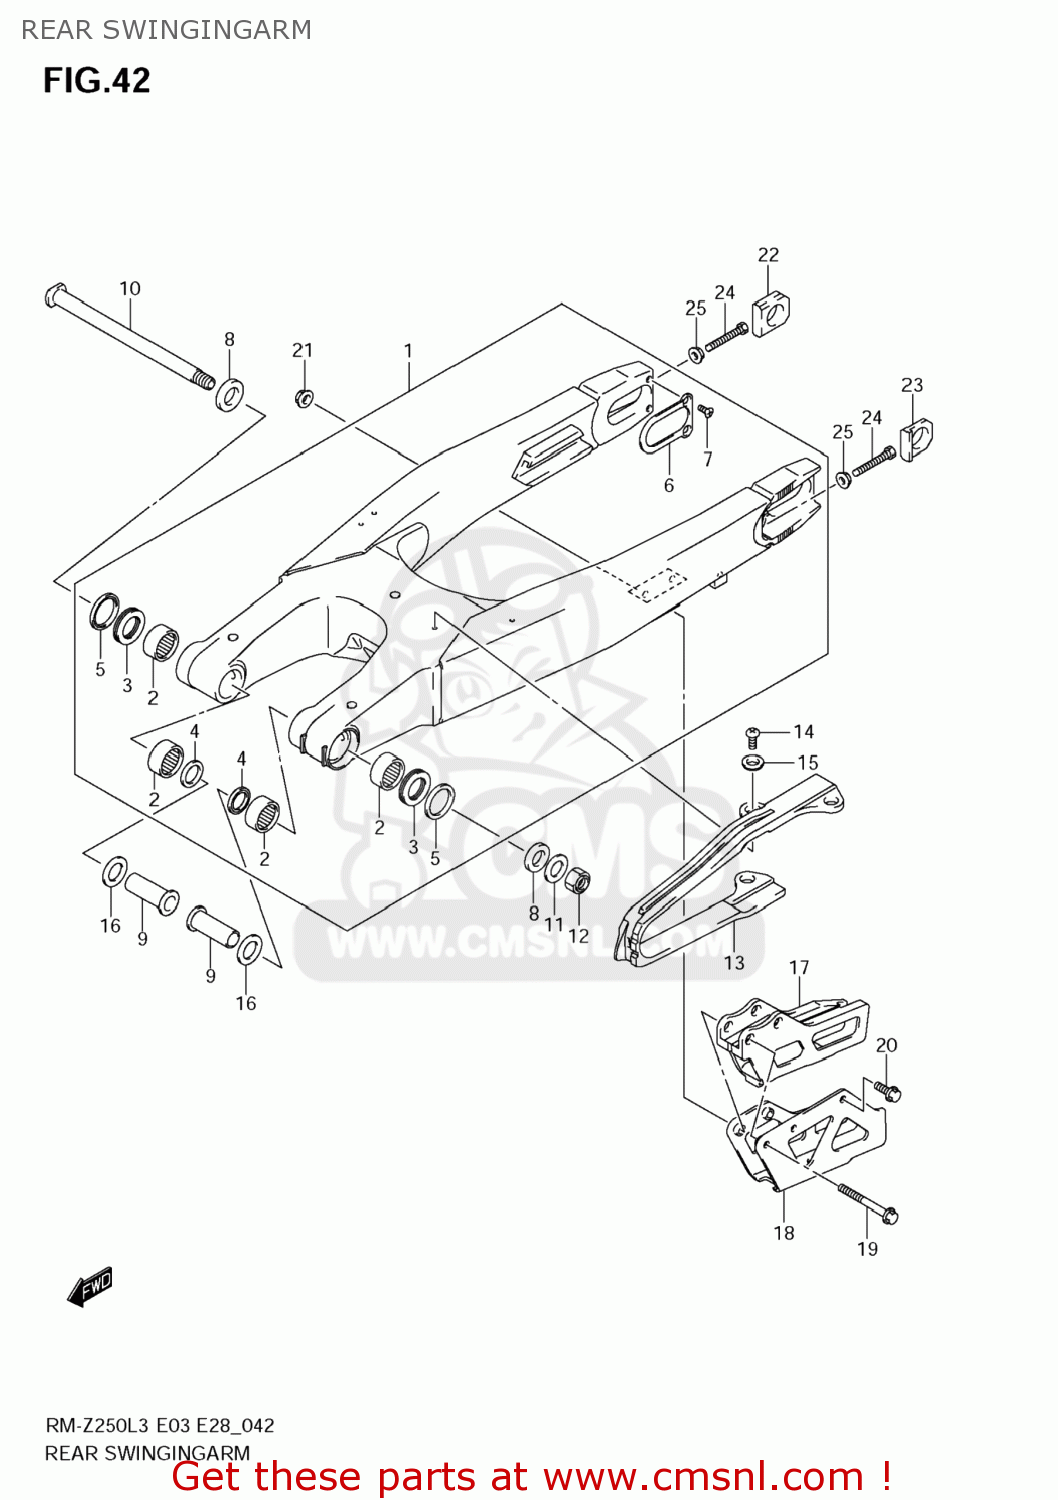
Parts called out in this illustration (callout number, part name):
1	SWINGINGARM ASSY,RR
2	BEARING(22X29X15)
3	BEARING(22X35X2)
4	SEAL,OIL(22X29X4)
5	SEAL,RR SWGARM PIVOT OUTER
6	PLATE,SWING ARM RR
7	SCREW(4X10)
8	SPACER,RR SWGARM PIVOT OUTER
9	SPACER,SWGARM PIVOT INNER
10	SHAFT,RR SWINGINGARM PIVOT
11	WASHER
12	NUT
13	BUFFER,CHAIN TOUCH DEFENSE
14	SCREW
15	WASHER
16	WASHER
17	GUIDE,CHAIN
18	PLATE,CHAIN GUIDE
19	BOLT(6X45)
20	BOLT(6X12)
21	NUT
22	WASHER,CHAIN ADJUSTER,R
23	WASHER,CHAIN ADJUSTER,L
24	BOLT(8X50)
25	NUT
